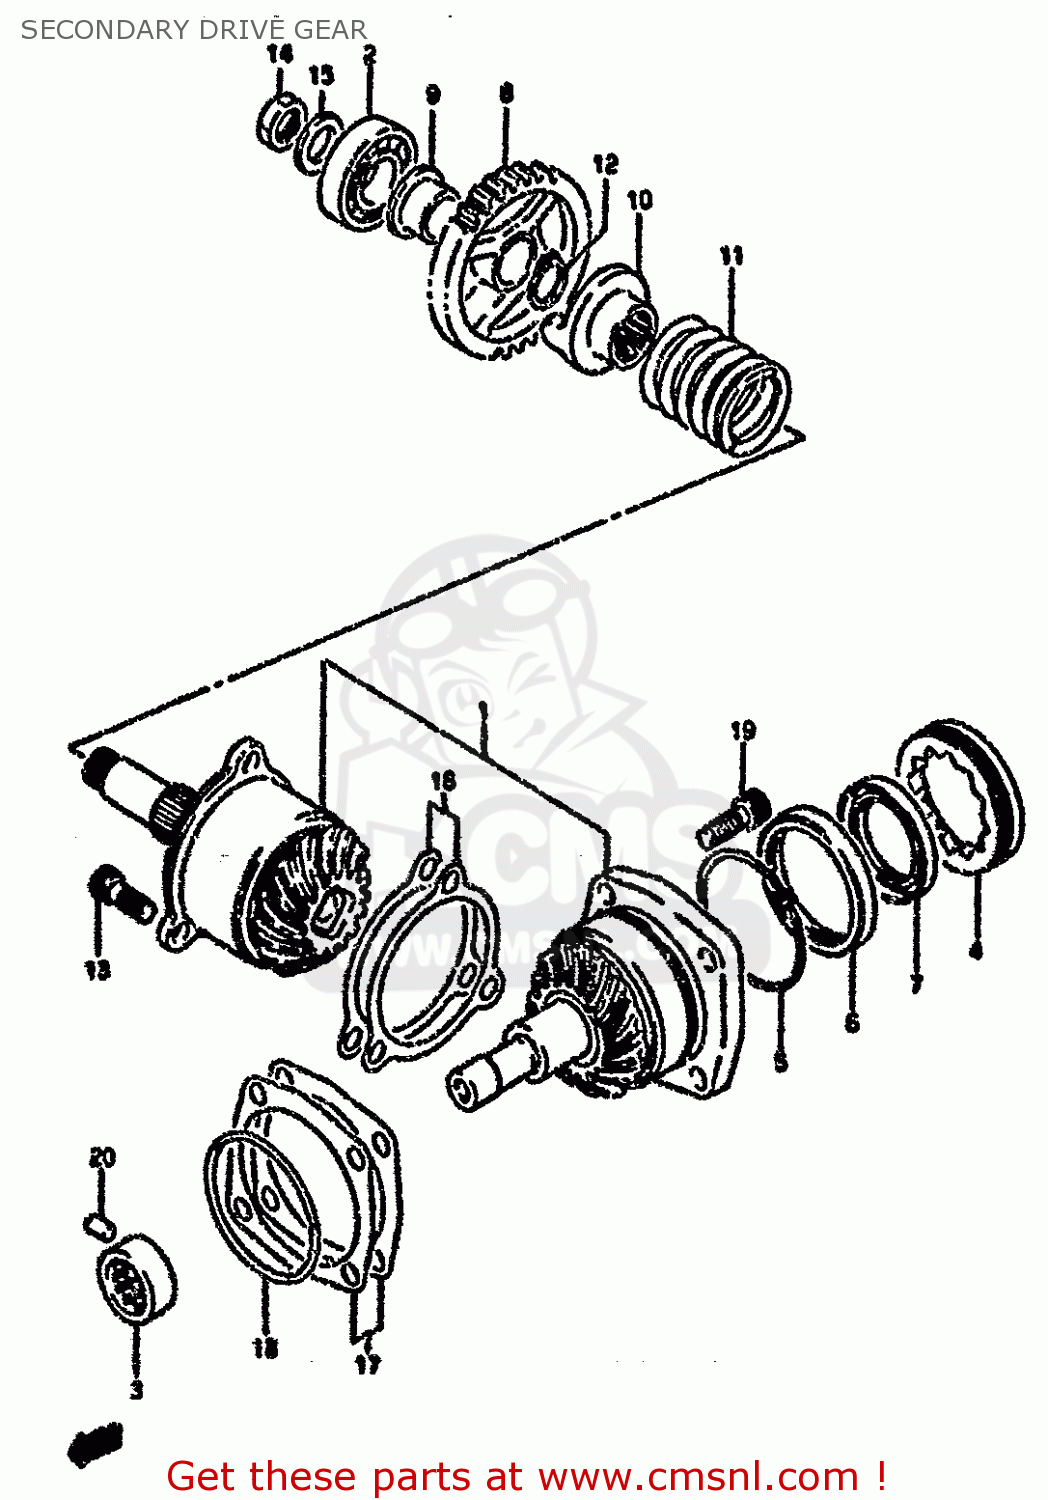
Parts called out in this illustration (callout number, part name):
1	GEAR & HOUSING SET,SECONDARY
2	BEARING(20X52X15)
3	BEARING(20X34X16)
4	STOPPER,SEC DRIVEN BEARING
5	O RING(D:1.2,ID:59.6)
6	HOUSING,OIL SEAL
7	SEAL,OIL(38X54X8.5)
8	GEAR,OVER DRIVING DRIVE
9	BUSH,REDUCTION DRIVEN GEAR
10	DOG,OUTPUT CAM
11	SPRING
12	CIRCLIP
13	BOLT
14	NUT
15	WASHER(16X29X4)
16	SHIM SET,SEC DRIVE GEAR
17	SHIM SET,SEC DRIVEN HOUSING
18	O RING(D:2.1,ID:66.2)
19	BOLT
20	PIN
